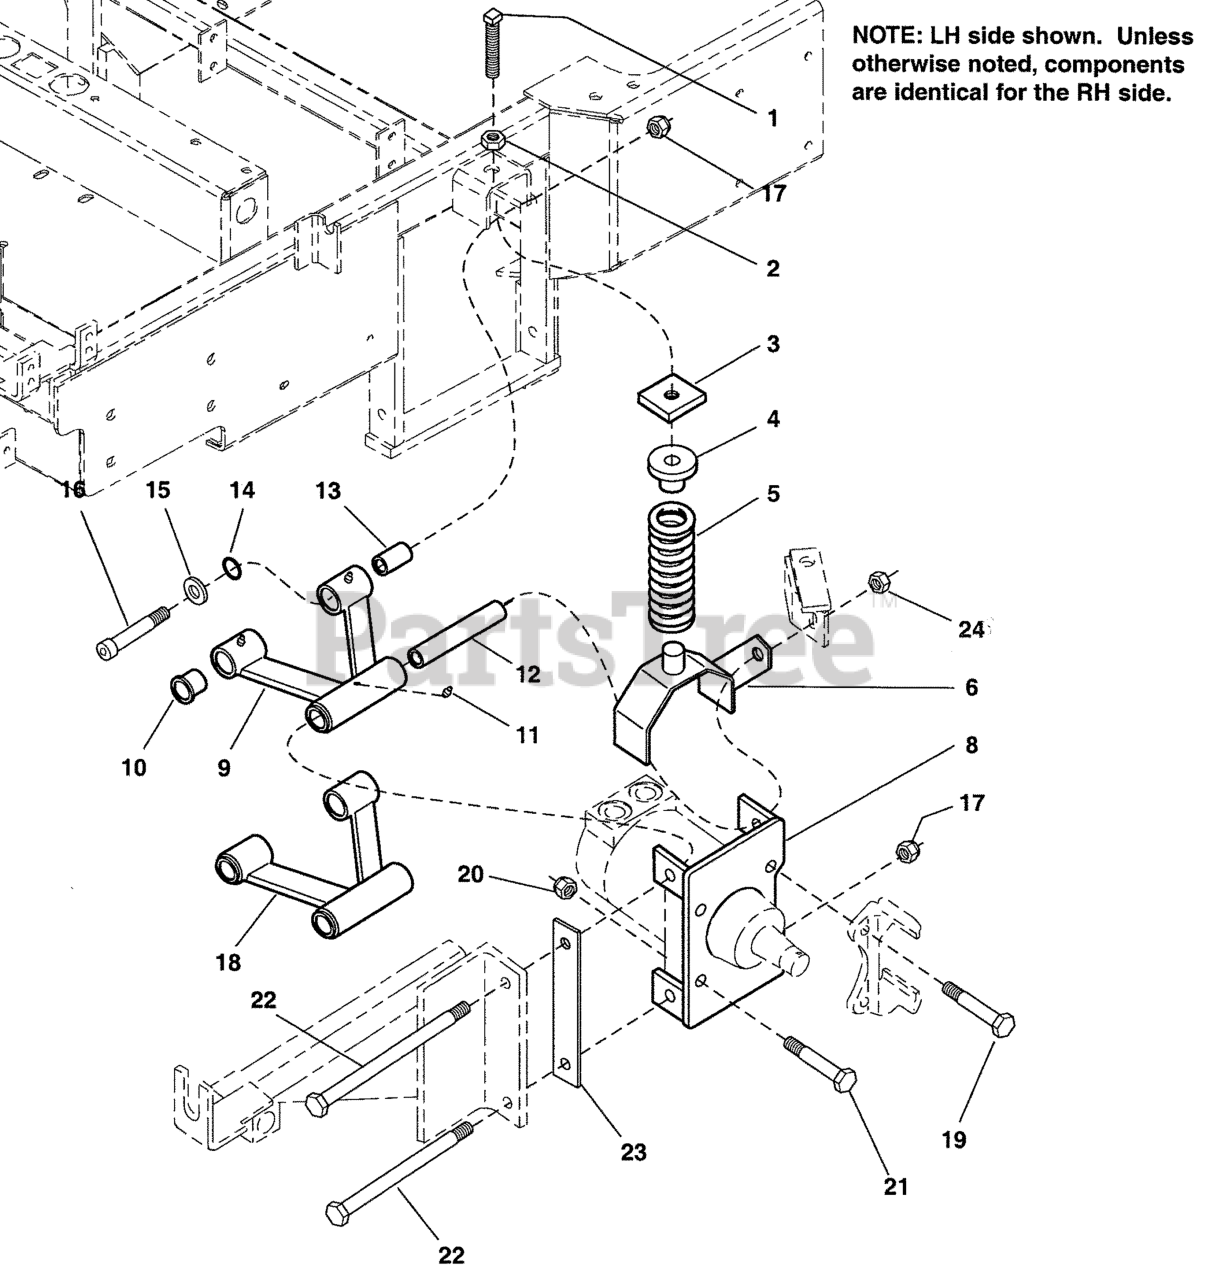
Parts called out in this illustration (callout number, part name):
1	SET SCREW, Square Hd, 1/2-13 x 3
2	NUT, Hex, Jam, 1/2-13
3	SPRING COMPRESSION PLATE
4	SPRING RETAINER
5	SPRING, SUSPENSION
6	SPRING SADDLE-LH
8	WHEEL MOTOR MOUNT
9	ASSM, UPPER A-ARM - RED
10	BUSHING, Flange
11	GREASE FITTING
12	PIVOT SLEEVE, Long
13	PIVOT SLEEVE, Short
14	O-RING
15	WASHER, A-Arm
16	CAPSCREW, Allen Head, 1/2-13 x 3
17	NUT, 1/2-13 HEX NYLON LOCK
18	LOWER A-ARM ASSEMBLY
19	BOLT, 1/2-20 x 3
20	NUT, Hex, Nylon Lock, 1/2-20
21	BOLT, 1/2-20 X 2-1/2" GD5 CZ
22	BOLT, 1/2-13 x 6-1/2
23	SPACER PLATE
24	NUT, Hex, Side Locking, 1/2-13
